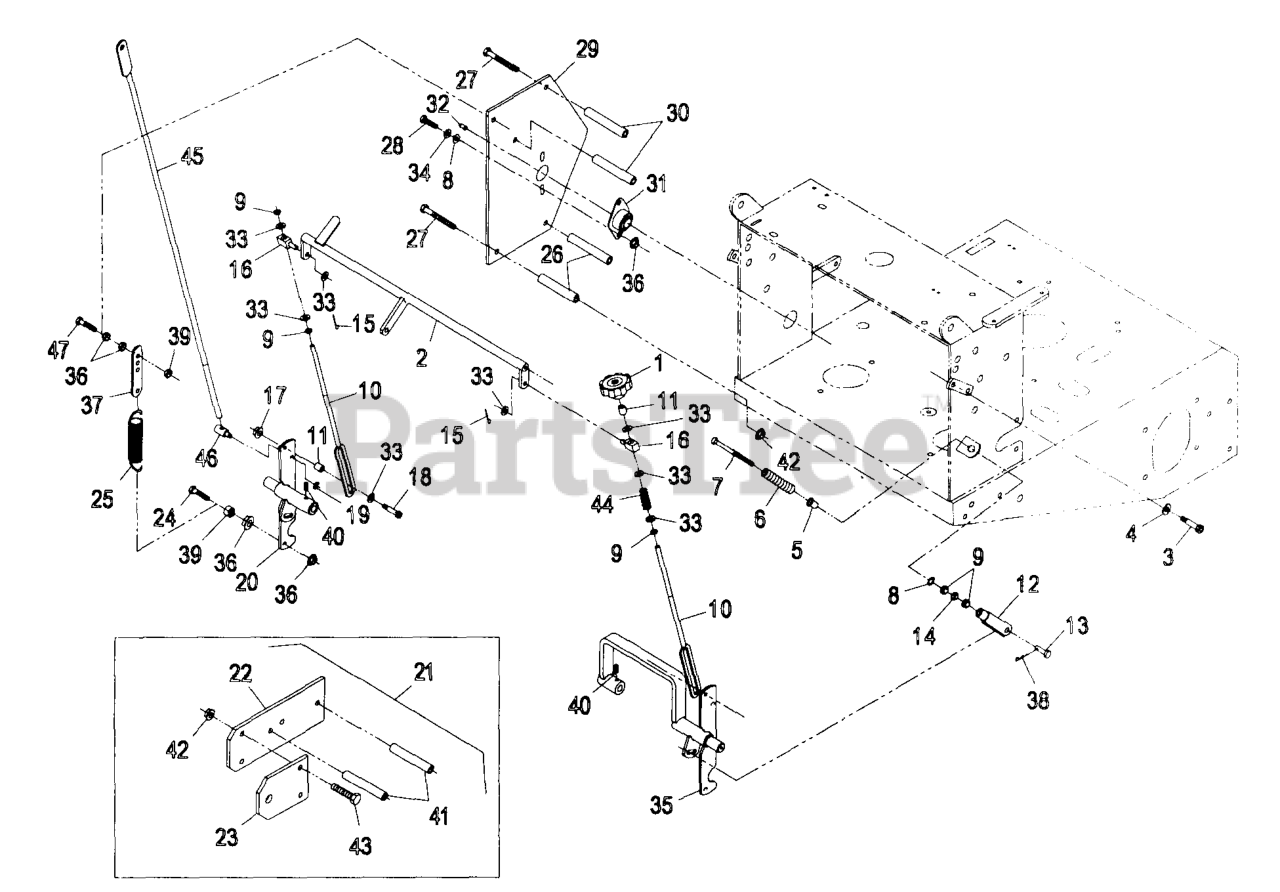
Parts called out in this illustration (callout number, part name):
1	KNOB-TRACKING
2	CRANK-CONTROL, SPEED
3	SCREW-HSH
5	BUSHING-FLANGED
6	SPRING-RETURN, NEUTRAL
7	BOLT-RETURN, NEUTRAL
10	LINK-CONTROL, SPEED
12	YOKE-ADJUSTABLE
13	PIN-CLEVIS
18	SCREW-HSH
21	Sulky Hitch Kit, (Vik Hydro)
22	MOUNT-HITCH
23	Bracket, Hitch Adapter
25	SPRING-EXTENSION
26	SPACER-SHIELD
30	SPACER-SHIELD
31	BEARING-FLANGE, SIDE
34	WASHER-LOCK
37	TAB-SPRING, EXTENSION
38	PIN-COTTER
40	SCREW-SET
44	SPRING-COMPRESSION
45	ROD-LEVER, DRIVE
47	BOLT-TAP, HH
